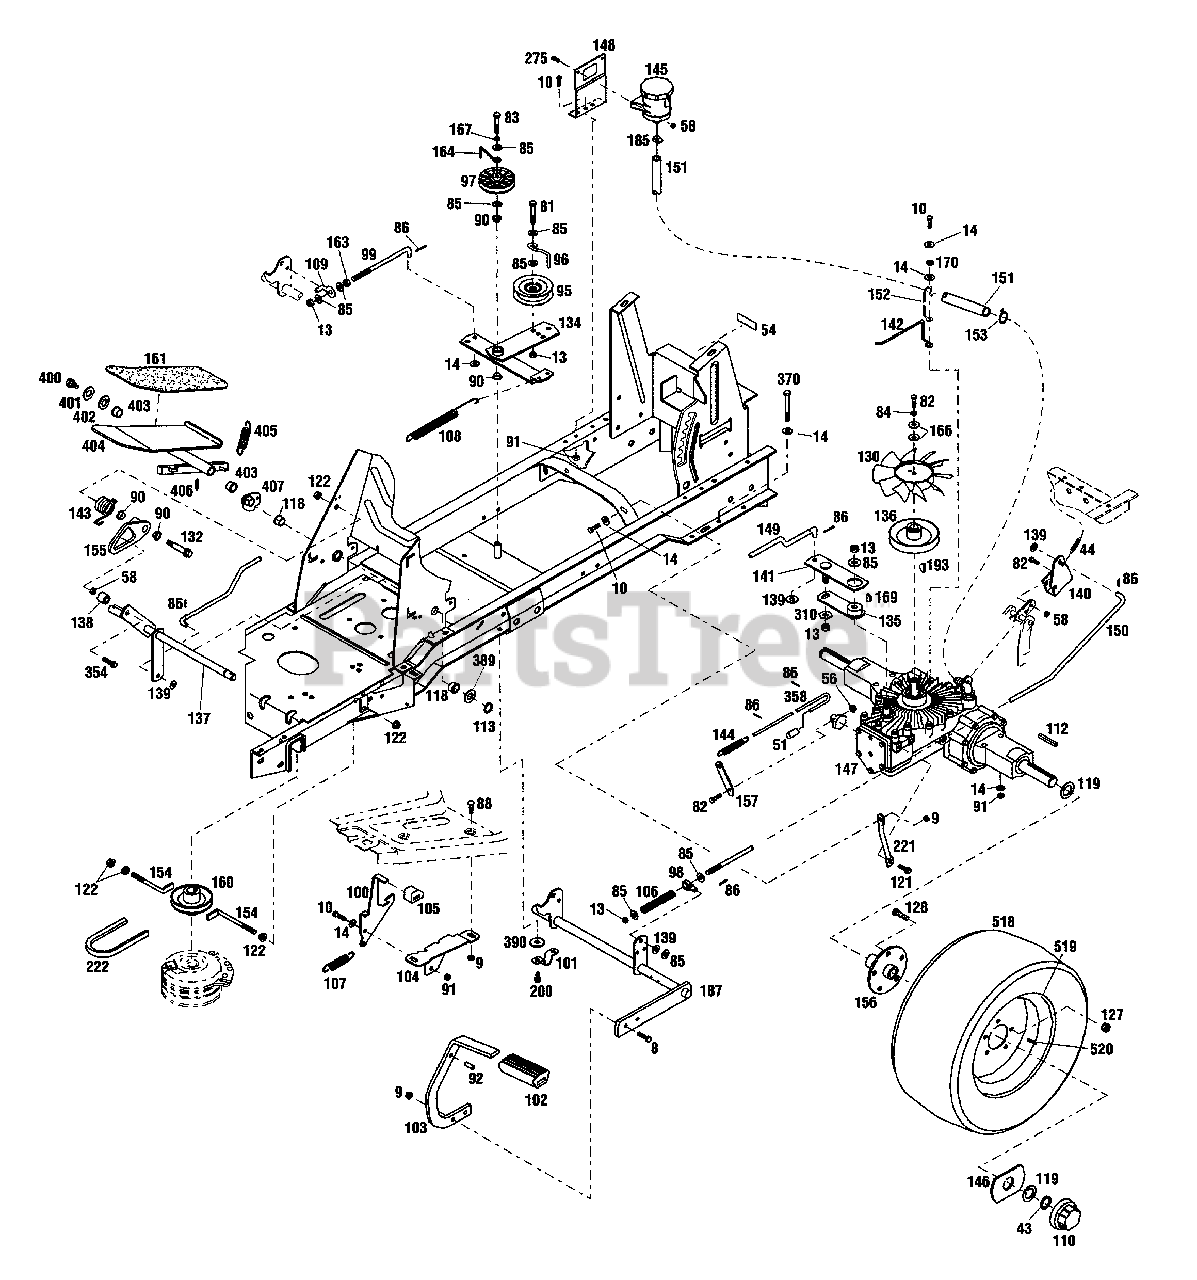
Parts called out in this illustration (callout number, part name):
8	Hex Head Screw, 5/16-18 x 1
9	Flange Nut, 5/16-18
10	Hex Head Screw, 5/16-18 x 3/4
13	Hex Top Locknut, 3/8-16
14	Flat Washer, 5/16
43	Retaining Ring, 3/4
44	Extension Spring
51	Handle Grip
54	Decal, Transmission Release
56	Flange Nut, 1/4-20
58	Top Lock Nut, 1/4-20
81	Hex Capscrew, 3/8-18 x 2
82	Hex Capscrew, 1/4-20 x 1
83	Hex Capscrew, 3/8-16 x 1-3/4
84	Lockwasher,1/4 SAE
85	Flat Washer, 3/8
86	Cotter Pin, 3/32 x 3/4
88	Carriage Bolt, 5/16-18 x 5/8
90	Nyliner Bushing
91	Locknut, 5/16-18
92	Drive Pin, 5/16 x 3/4
95	Idler Pulley
96	Belt Guide
97	Idler Pulley
98	Swivel
99	Clutch Rod
100	Brake Lock Latch
101	Clip, 3/4
102	Foot Pedal Pad
103	Brake Pedal
104	Brake Lock Bracket
105	Parking Brake Pedal Pad
106	Compression Spring
107	Extension Spring
108	Extension Spring
109	Pivot Rod
110	Hub Cap
112	Square Key, 1/4 x 2
113	Retaining Ring, 5/8
118	Flange Bearing, 5/8
119	Washer, 1-1/64
121	Lock Screw, 5/16-18 x 1/2
122	Flange Nut, 3/8-16
127	Lug Nut, 7/16-20
128	Wheel Stud
132	Shoulder Screw
134	Idler Arm Assembly
135	Hydro Arm
136	Eaton Hydro Sheave
137	Hydro Pivot Shaft
138	Ball Bearing
139	Flat Washer, 3/8
140	Hydro Brake Bracket
141	Hydro Control Arm
142	Belt Guide
143	Torsion Spring
144	Extension Spring
145	Expansion Tank
146	Special Washer, 1 x 2 1/2
147	Transmission, Eaton 751
148	Expansion Tank Support
149	Hydro Control Rod
150	Brake Rod
151	Hose, 5/8
152	Hose Support
153	Hose Clamp, 5/8
154	Belt Guide
155	Hydro Neutral Return
156	Wheel Hub
157	Dump Valve
160	Engine Sheave
161	Foot Pedal Pad
163	Hex Nut, 3/8-16
164	Belt Guide
166	Washer, 1/4 x 1-1/4
167	Lockwasher, 3/8
169	Woodruff Key, 1/8 x 1/2
170	Lockwasher, 5/16
185	Hose Clamp
187	Brake Pedal Assembly
193	Woodruff Key, 3/16 x 5/8
200	Flange Screw, 5/16-18 x 3/4
221	Transmission Support
275	Hex Head Screw, 1/4-20 x 5/8
310	Lockwasher, 3/8
354	Flange Screw, 1/4-20 x 1-1/4
358	Dump Valve Rod
370	Capscrew, 5/16-18 x 3
389	Flat Washer, 5/8
390	Flat Washer, 3/8
400	Shoulder Screw, 5/8 x 2
401	Flat Washer, 5/8
402	Flat Washer, 5/8
403	Flange Bearing
406	Roll Pin
407	Cam Assembly
518	Tire, 23 x 10.5-12, Multi Trac CS
520	Valve Stem
